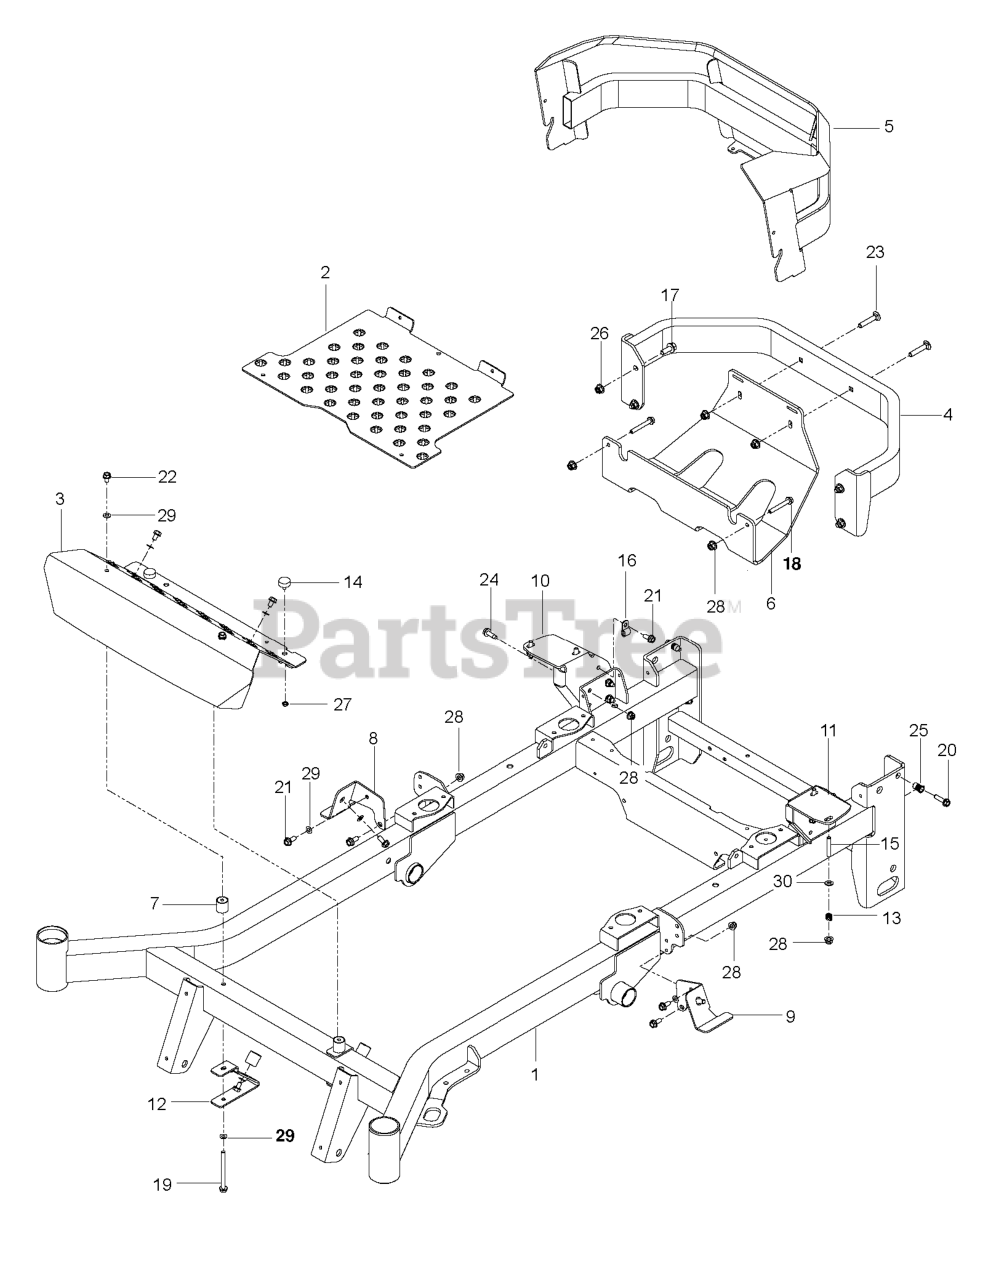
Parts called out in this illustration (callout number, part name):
1	FRAME W/DECALS PZ 72
2	PLATE, FLOOR PAN, OR
3	PLATE, FOOT REST, OR
4	BUMPER.REAR.ORANGE
5	GUARD, REAR, GRAY
6	PLATE, SKID GRAY
7	MOUNT, F/F INSERT
8	MOUNT, RT TANK, BLK
9	MOUNT, LT TANK, BLK
10	XX MOUNT, TANK, RT-BLK
11	MOUNT, TANK, LT-BLK
12	BRACKET, REST MOUNT
14	BUMPER, 1/4-20 STUD, 1/4
15	STUD, 5/16C
16	DOUBLE TUBE CLAMP
17	HHFS 3/8-16 X 1 GRD 5 ZD
18	HHFS 5/16-18 X 2.25 GD 5
19	HHFS 5/16-18 X 3 3/4
20	HHFS 5/16-18 X 1.25 TPBLT GD 5
21	HHFS 5/16-18 X 3/4
22	SCR 5/16-18 X 1/2 SELFTAP ZN
23	RHSNB 3/8C X 2
24	RP BLT 5/16-18 X 1 THRD FORM D
25	NUTSERT 5/16-18 THICK GRIP
26	NUT 3/8-16 HEX FLG NYLOC ZD
27	JAM NUT 1/4C (2 2 PW01)
28	5/16-18 NYLOC FLANGE NUT
29	WASH 5/16 DISC SPRING ZD
30	FLAT WASHER 5/16 SAE
